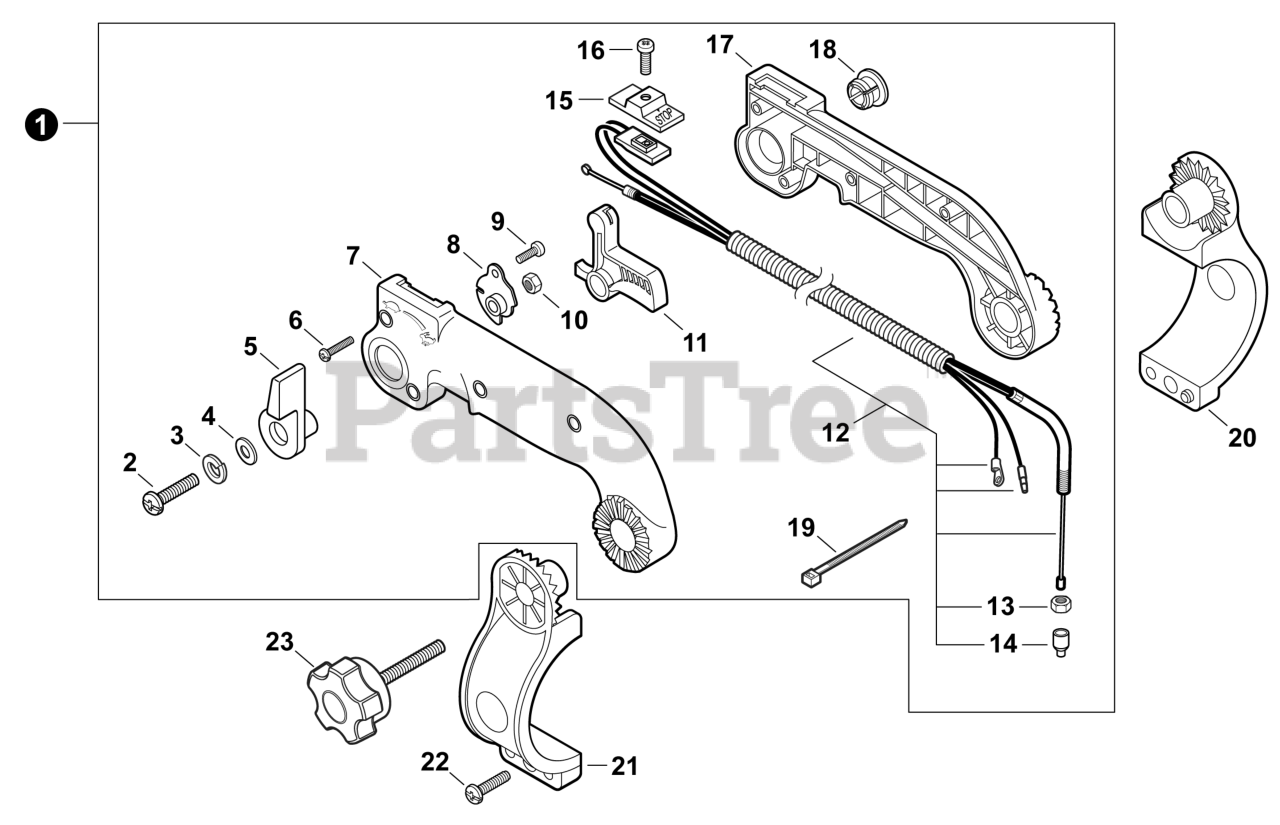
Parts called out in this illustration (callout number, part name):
1	THROTTLE CONTROL KIT - TUBE MOUNT
2	SCREW 6×20
3	WASHER, SPRING 6
4	WASHER 6.5×13×1
5	CONTROL, THROTTLE
6	SCREW 4×22
7	CONTROL HANDLE - LEFT
8	BRACKET, THROTTLE
9	SCREW 4×10
10	NUT, HEX M6
11	TRIGGER, THROTTLE
12	CABLE ASSY, CONTROL
13	NUT, HEX M6
14	CAP, DUST
15	KNOB, SWITCH - ORANGE
16	SCREW 3×10
17	CONTROL HANDLE - RIGHT
19	STRAP, TIE
20	BRACKET, RIGHT
21	BRACKET, LEFT
22	BOLT, TORX 5×20
23	KNOB, SCREW
